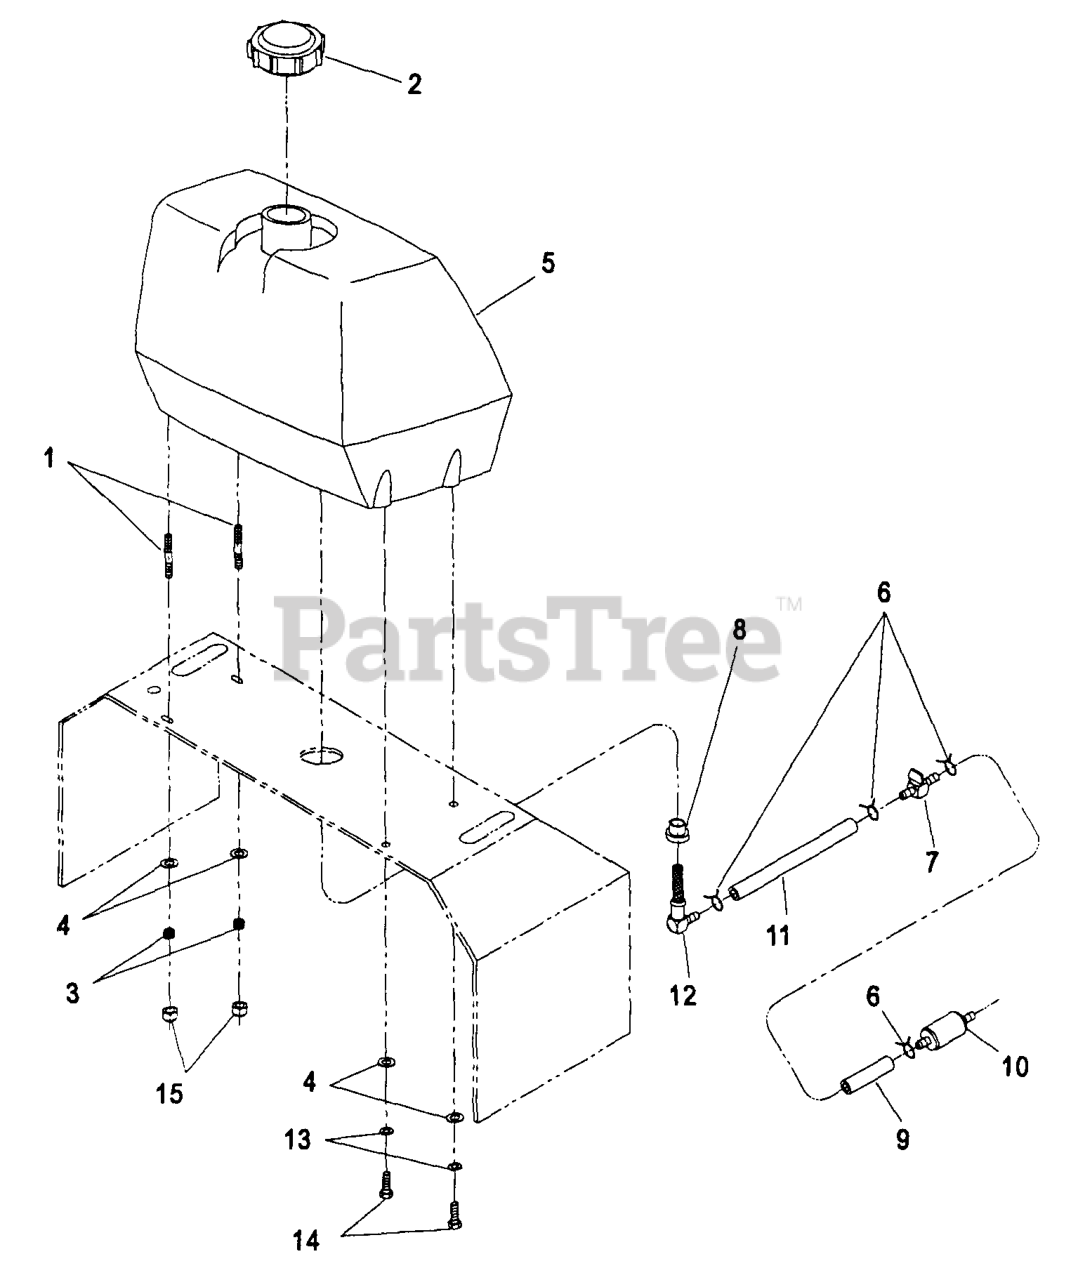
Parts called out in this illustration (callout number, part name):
1	STUD
2	CAP-FUEL
3	SPRING-TANK, FUEL
7	VALVE-FUEL
9	HOSE-LINE, FUEL
10	Kohler Part No. 2405002 Fuel Filter
12	ELBOW-TANK, FUEL
13	WASHER-LOCK
